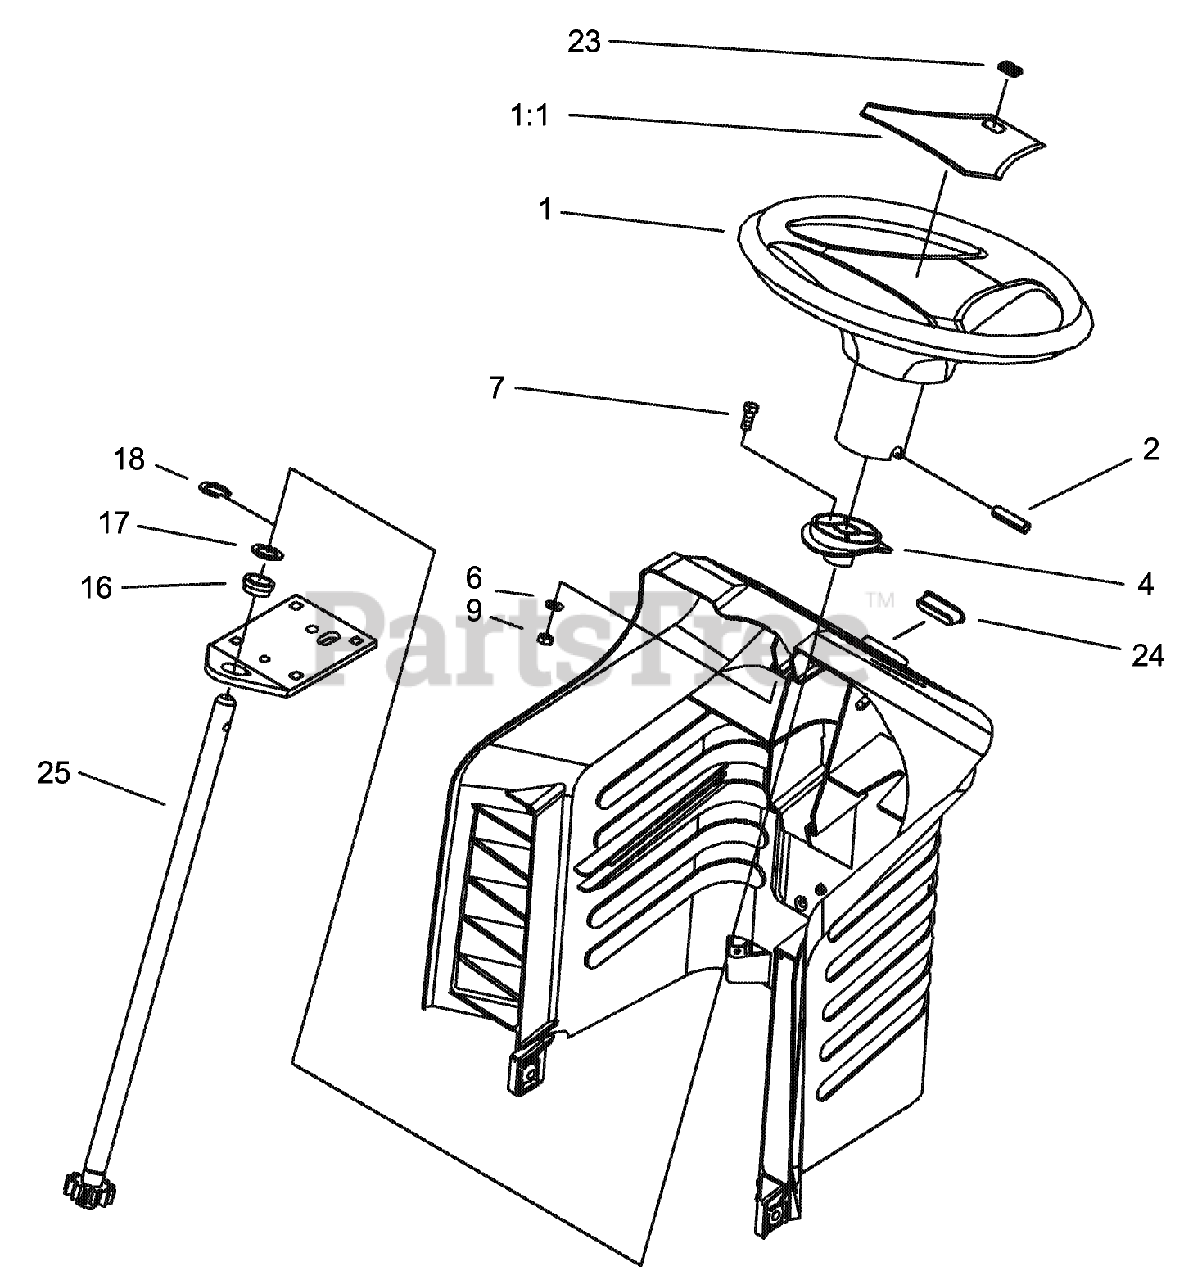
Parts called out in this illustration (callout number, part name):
1	STEERING WHEEL ASM
1:1	COVER-WHEEL, STEERING
2	PIN-ROLL
4	BUSHING-SLIDING
6	WASHER-FLAT
7	SCREW-HH
9	NUT-LOCK, NI
16	BEARING-FLANGE
17	WASHER-THRUST
18	E-RING
23	DECAL
25	SHAFT-STEERING, LONG
